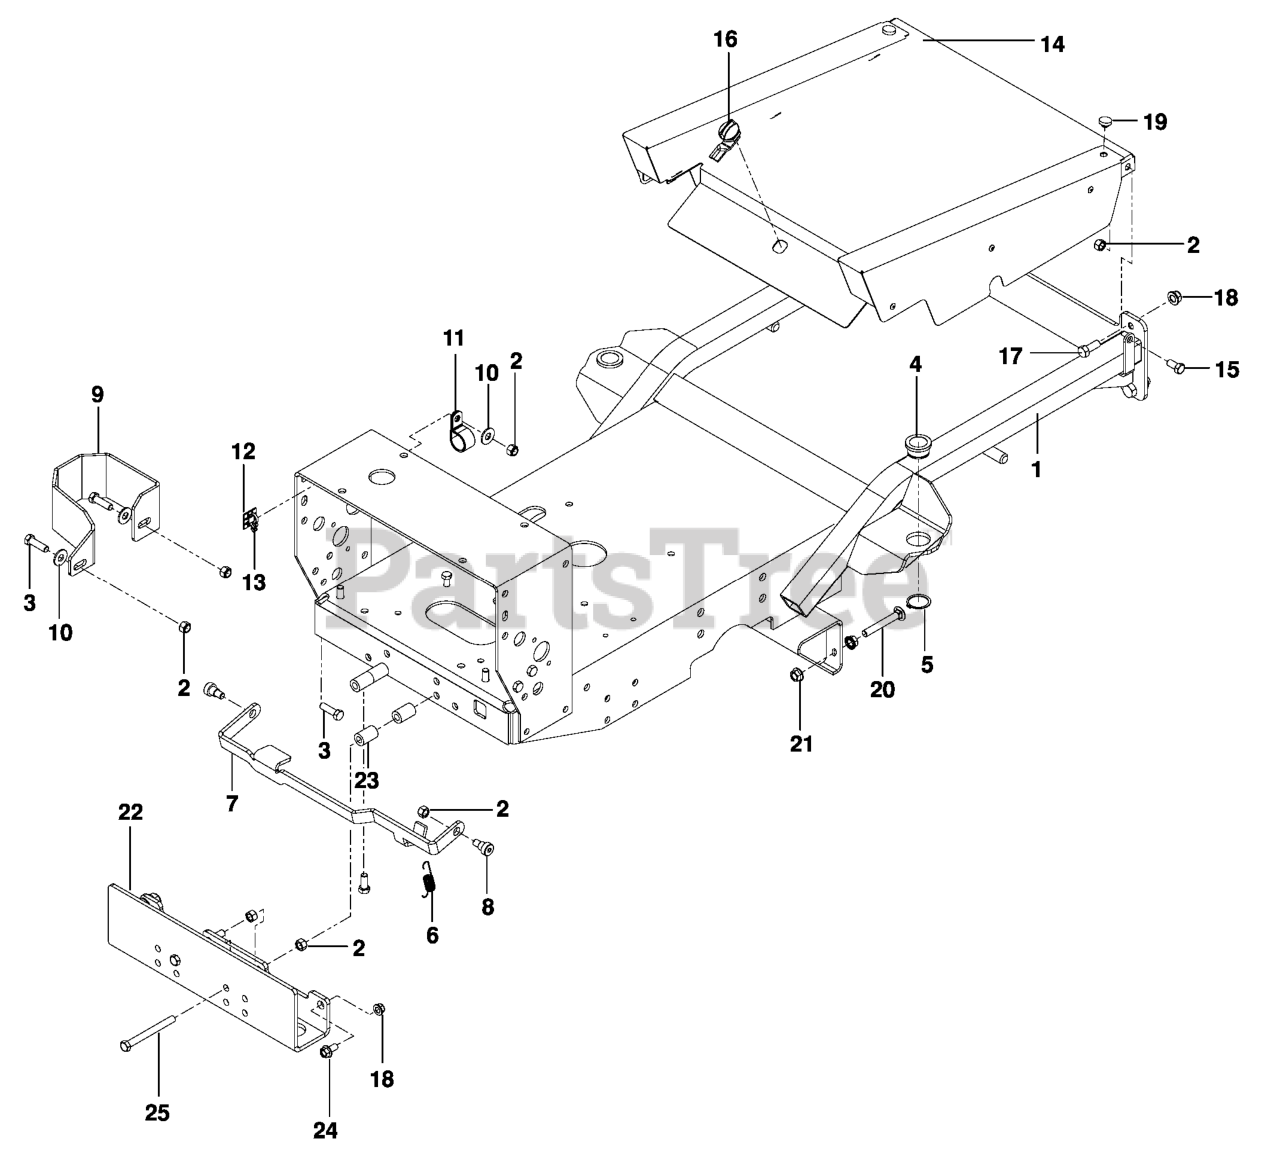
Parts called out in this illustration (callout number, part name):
1	CHASSIS WLDT ORANGE
2	NUT 3/8-16 NYLOC
3	HCS 3/8C X 1 1/4 GR5
4	BUSHING, BRONZE HOC
5	SNAP RING 1.25
6	SPRING, EXTENSION
7	BAR, THROWOUT OR
8	SB 3/8-16 X 3/8 SKT HD ZD
9	GUARD FILTER PAINTED
10	WASHER 3/8 FLAT
12	MOUNTING BLOCK CABLE TIE
13	TIE, PLASTIC
14	COVER, ASM, CENTER
15	SCREW 3/8C X 3/4 HEX CAP
16	LATCH, SHORT WING
17	HCS 1/2-13 X 1-1/4
18	NUT, 1/2-13 HEX FLG NYLOC ZD
19	GROMMET, BUMPER
20	RHSNB 3/8-16 x 2¾
21	NUT 3/8C WHIZ
22	BUMPER, OR
24	HHFS 1/2-13 X 1 GR5 ZD
25	HCS3/8-16.X
26	HCS3/8-16.X
28	HHFS 1/2-13 X 1 GR5 ZD
